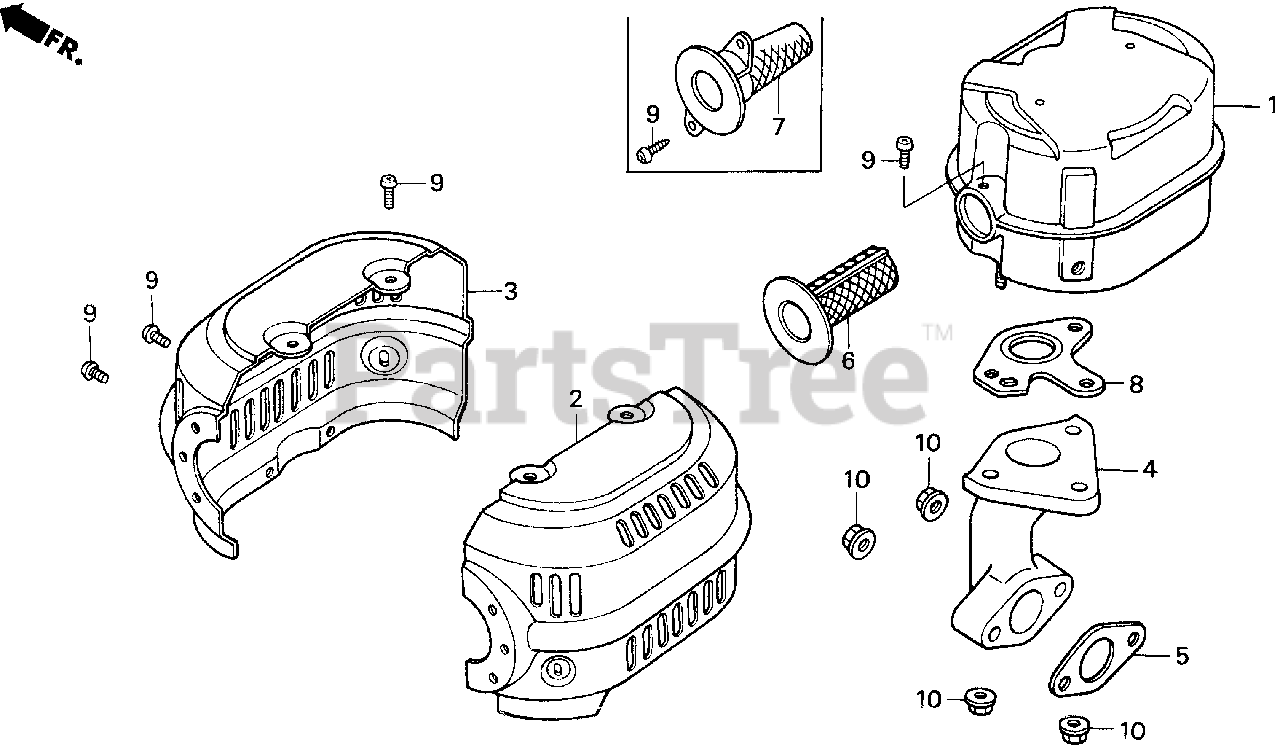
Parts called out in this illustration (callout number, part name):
1	MUFFLER (SILENT)
2	PROTECTOR, R. MUFFLER (SILENT)
3	PROTECTOR, L. MUFFLER (SILENT)
5	GASKET, EX. PIPE
5	GASKET, EX. PIPE (WACKER)
6	ARRESTER, SPARK
8	GASKET, MUFFLER (ARRESTER)
9	SCREW, TAPPING (5X8)
10	NUT, FLANGE (8MM)
